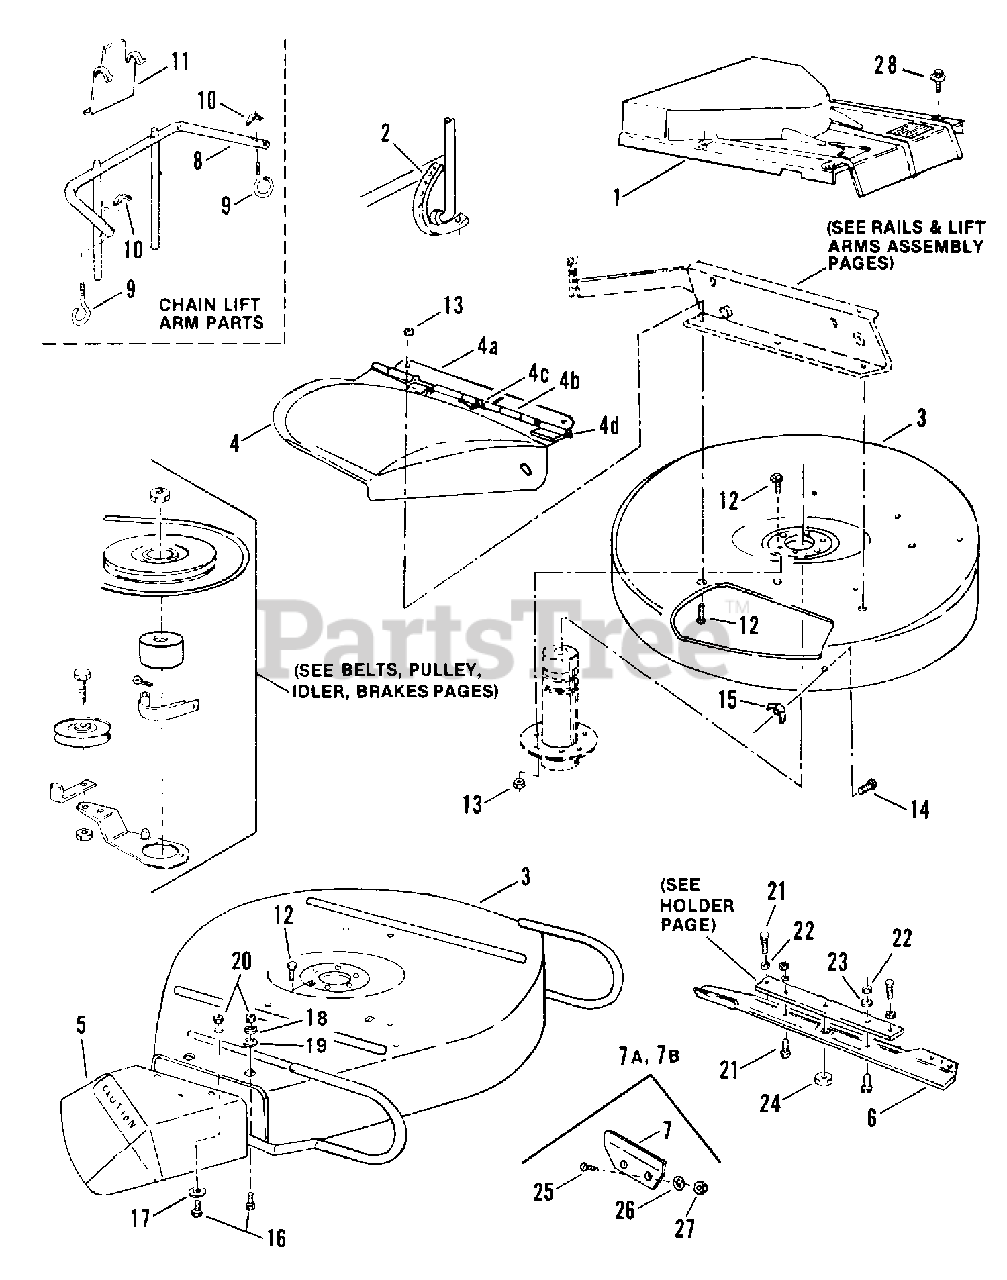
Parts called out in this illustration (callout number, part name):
1	COVER, Spindle
2	INDICATOR PLATE
3	25" DECK (Includes decals)
3	26" DECK (Includes decals & deflector)
3	28" DECK (Includes decals)
3	30" DECK (Includes decals & deflector)
3	33" DECK (Includes decals)
4	28" & 33" DEFLECTOR ASSY (Plastic with 5 hole hinge)
4	28" & 33" DEFLECTOR ASSY (Plastic with 8 hole hinge)
4A	HINGE, (5 Mounting Holes)
4A	HINGE, (8 Mounting Holes)
4B	PIN/ROD, Hinge (.25" DIA 19.5" to .10" Hole)
4B	PIN/ROD, Hinge (.25" DIA 16.25" Long)
4C	SPRING, Hinge
4D	COTTER PIN, 3/32X3/4 YZ
4D	PALNUT, Washered .25"
5	DEFLECTOR, 26 & 30" Mowers
6	25" BLADE
6	26" BLADE
6	28" BLADE
6	30" BLADE
6	33" BLADE
7	AIR LIFT-26 & 30" Models (2 hole)
7	AIR LIFT-28 & 33" Models (3 hole)
7A	AIR LIFT KIT, Standard (2 hole)
7B	AIR LIFT KIT, Hi-Vac (3 hole)
8	ARM, Chain Lift
9	HOOK, Chain
10	NUT, Chain Adjusting
11	SHIELD, Engine Exhaust Heat
12	SCREW, 3/8-24x3/4 Hex Head Cap
13	LOCKNUT, 3/8-24 Hex
14	BOLT, 5/16Cx3/4 Carriage
15	WING-NUT, 5/16C
16	SCREW, 1/4-28x3/4 Hex Head Cap
17	WASHER, Fender
18	LOCKWASHER, 1/4 Internal Tooth
19	WASHER, 1/4 SAE
20	NUT, 1/4-28 Hex
21	SCREW, 1/2-20X1 Hex Head Cap
22	JAM-NUT, 1/2-20
23	LOCKWASHER, 1/2 Internal Tooth
24	LOCKNUT, 5/8-18 Hex
25	SCREW, 5/16-24 Machine
26	LOCKWASHER, 5/16 Internal Tooth
27	NUT, 5/16-24 Hex
28	HWST, 1/4C X5/8 BZ
